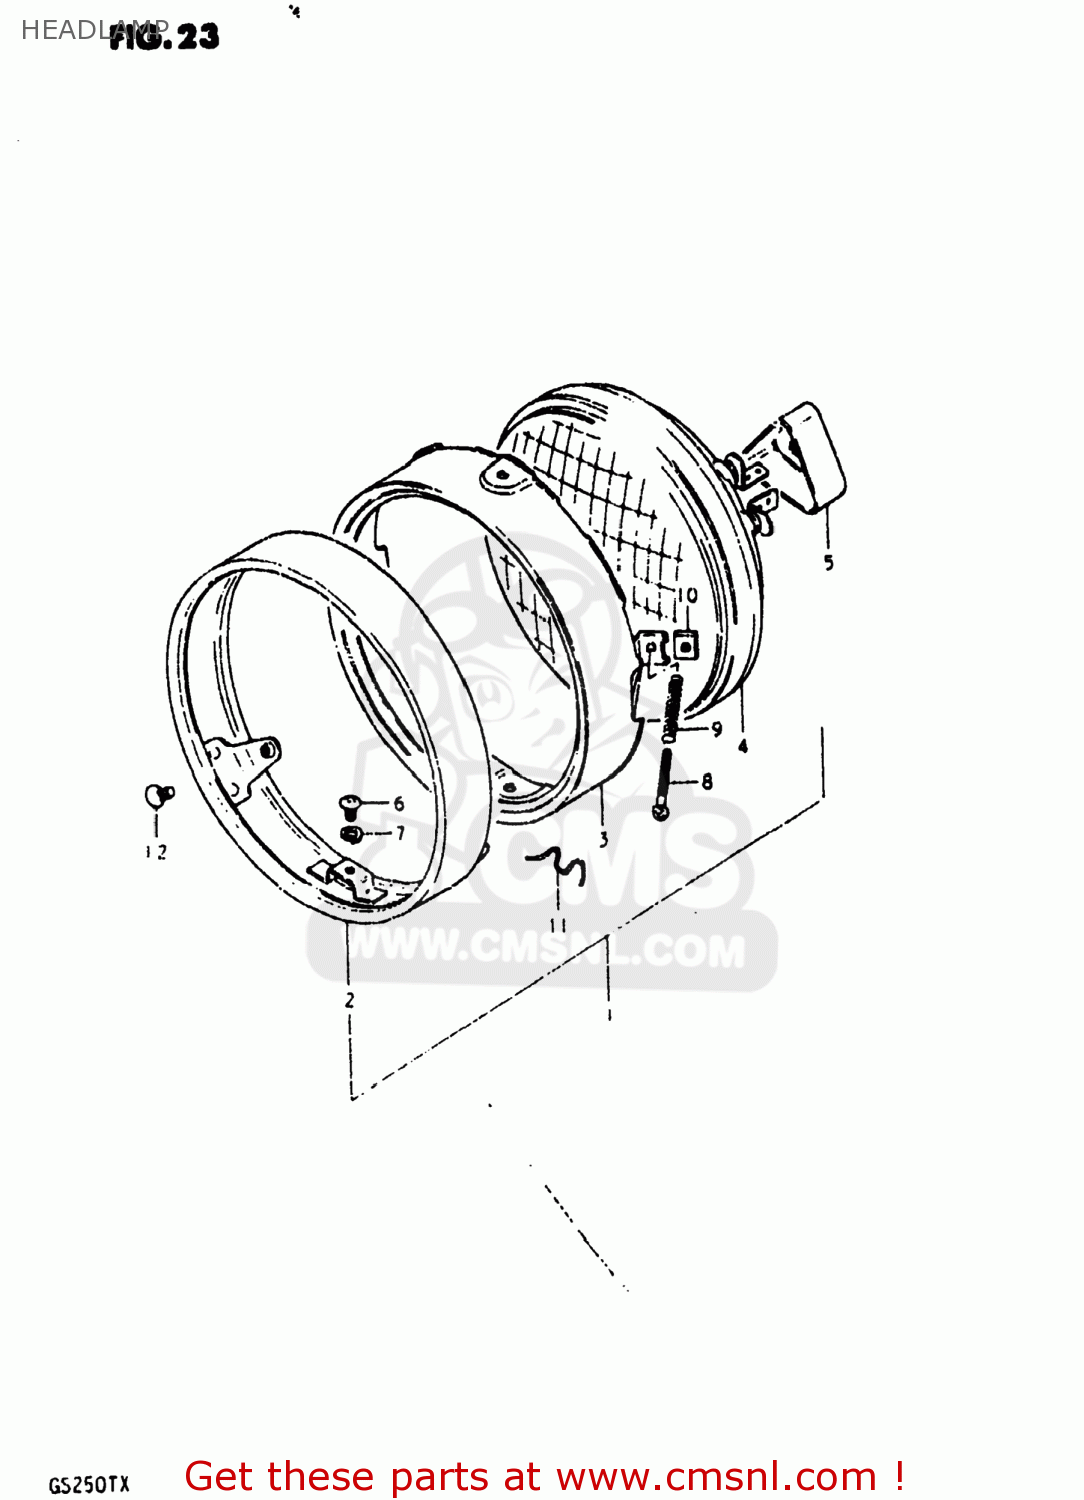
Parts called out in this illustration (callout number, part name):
1	LAMP ASSEMBLY,HEAD
2	RIM
3	RETAINER
4	LAMP UNIT
5	COVER
6	SCREW
7	LOCK WASHER
8	SCREW
9	SPRING
10	NUT
11	SPRING,HEAD LAMP UNIT
12	SCREW
